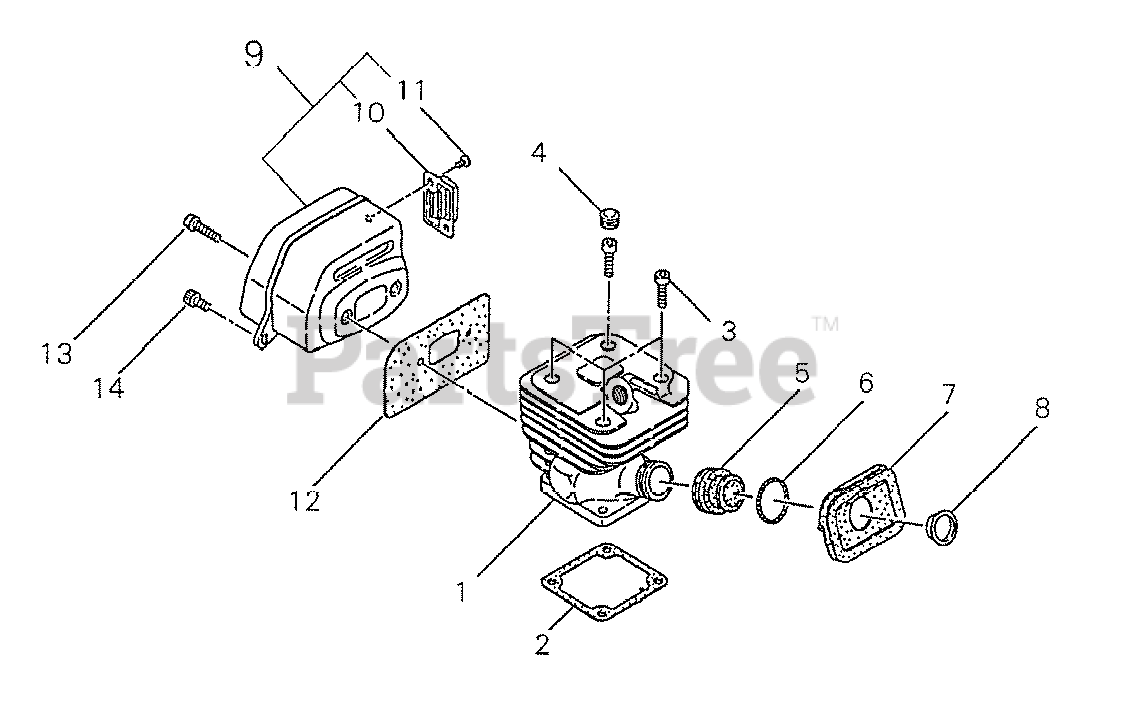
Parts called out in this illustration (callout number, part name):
1	CYLINDER
2	GASKET, CYLINDER
3	BOLT M5×18
4	PLUG
5	BOOT
6	SPRING
7	SEAL
8	SLEEVE
9	MUFFLER KIT
10	DEFLECTOR, EXHAUST
11	SCREW
12	SHIELD, EXHAUST
13	BOLT M5×18
14	BOLT 5×12
